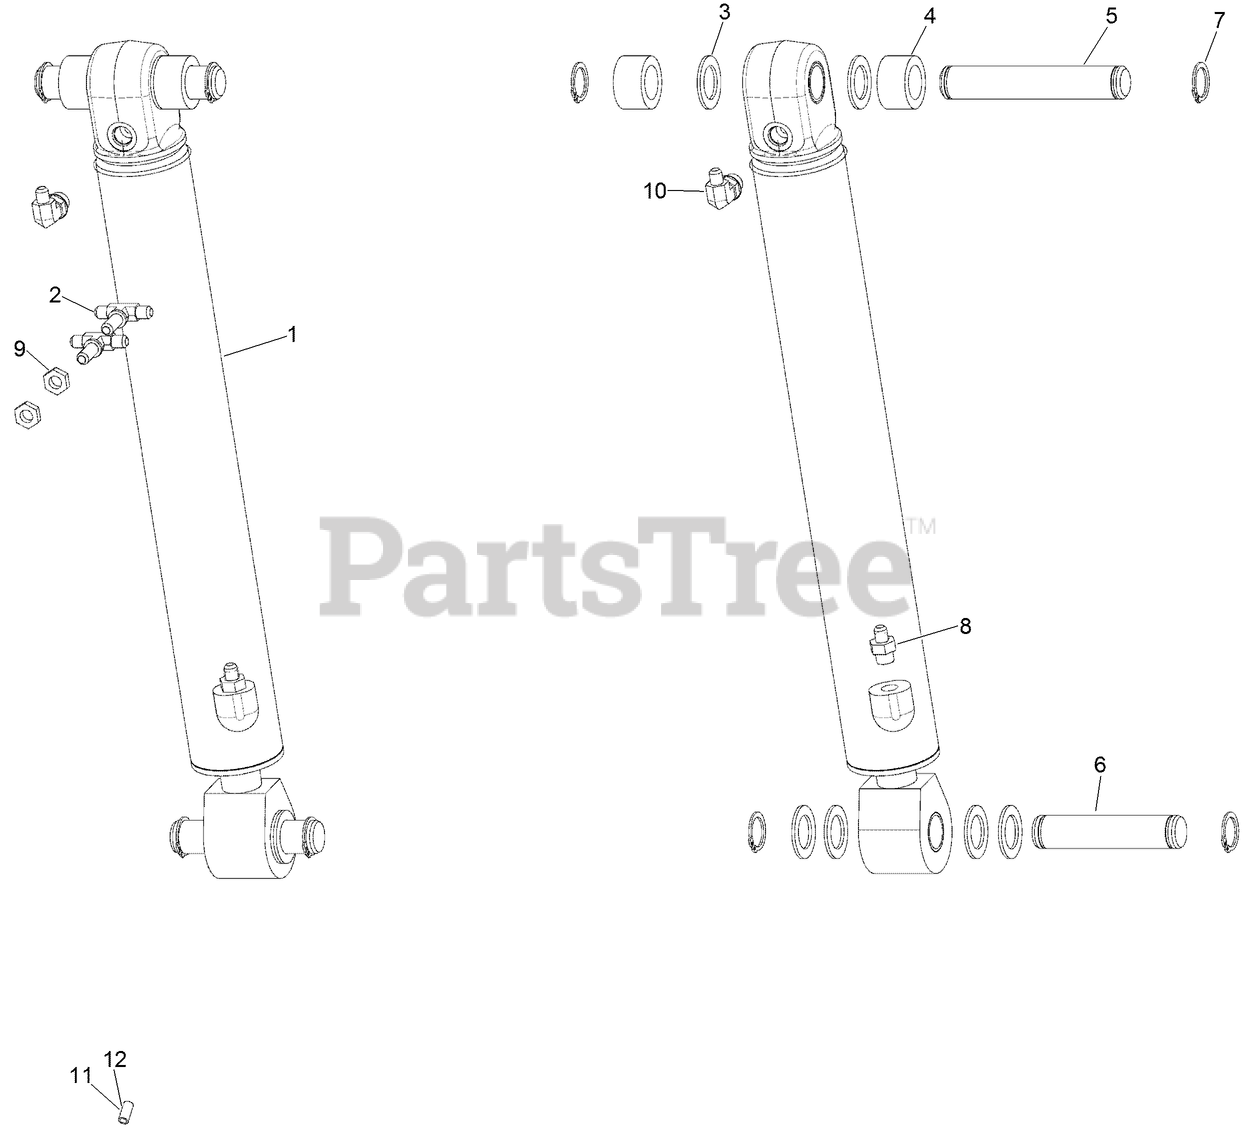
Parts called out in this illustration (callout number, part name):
1	CYLINDER-76 (3) ID x 498 mm (19-5/8 inch) Stroke, Dipper
2	TEE - Bulkhead BR 37FL 3/8 x 3/8 x 3/8
4	SPACER - Pin
5	PIN-PIVOT
7	RING-RETAINING
8	CONNECTOR
9	NUT-LOCK, BULKHEAD
10	ELBOW-90 Adj 37FL, 3/8 x 1/2 Tube
11	ASSEMBLY - Hose
12	ASSEMBLY - Hose
